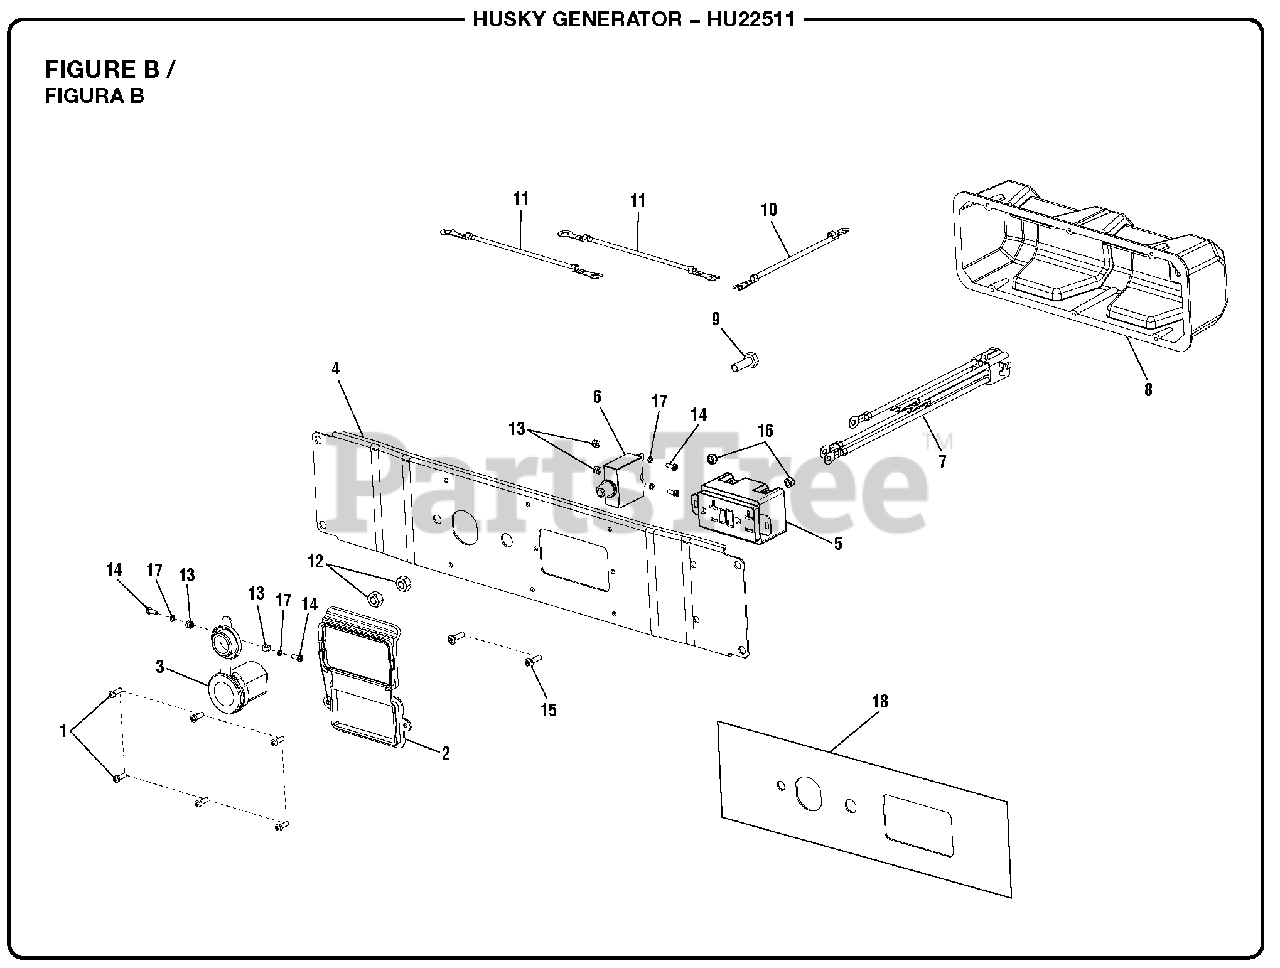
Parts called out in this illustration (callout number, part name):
1	Screw (6-20 x 3/8 in., Pan Hd.)
2	Outlet Cover (120 Volt)
3	DC Voltage Outlet
4	Front Panel
5	120 Volt GFCI Recepticle
6	Circuit Breaker (20 Amp, 125 Volt)
7	Socket Connector Assembly (9 Pin)
8	Back Panel
9	Bolt (1/4-20 x 5/8 in., Hex Hd.
10	Black Lead Assembly
11	Ground Wire Assembly
12	Hex Nut (1/4-20)
13	Lock Nut (M3)
14	Bolt (M3 x 8 mm)
15	Bolt (M4 x 12 mm, Button Hd.)
16	Flange Nut (M4 x 0.7)
17	Lock Washer
18	Power Outlet Panel Label
